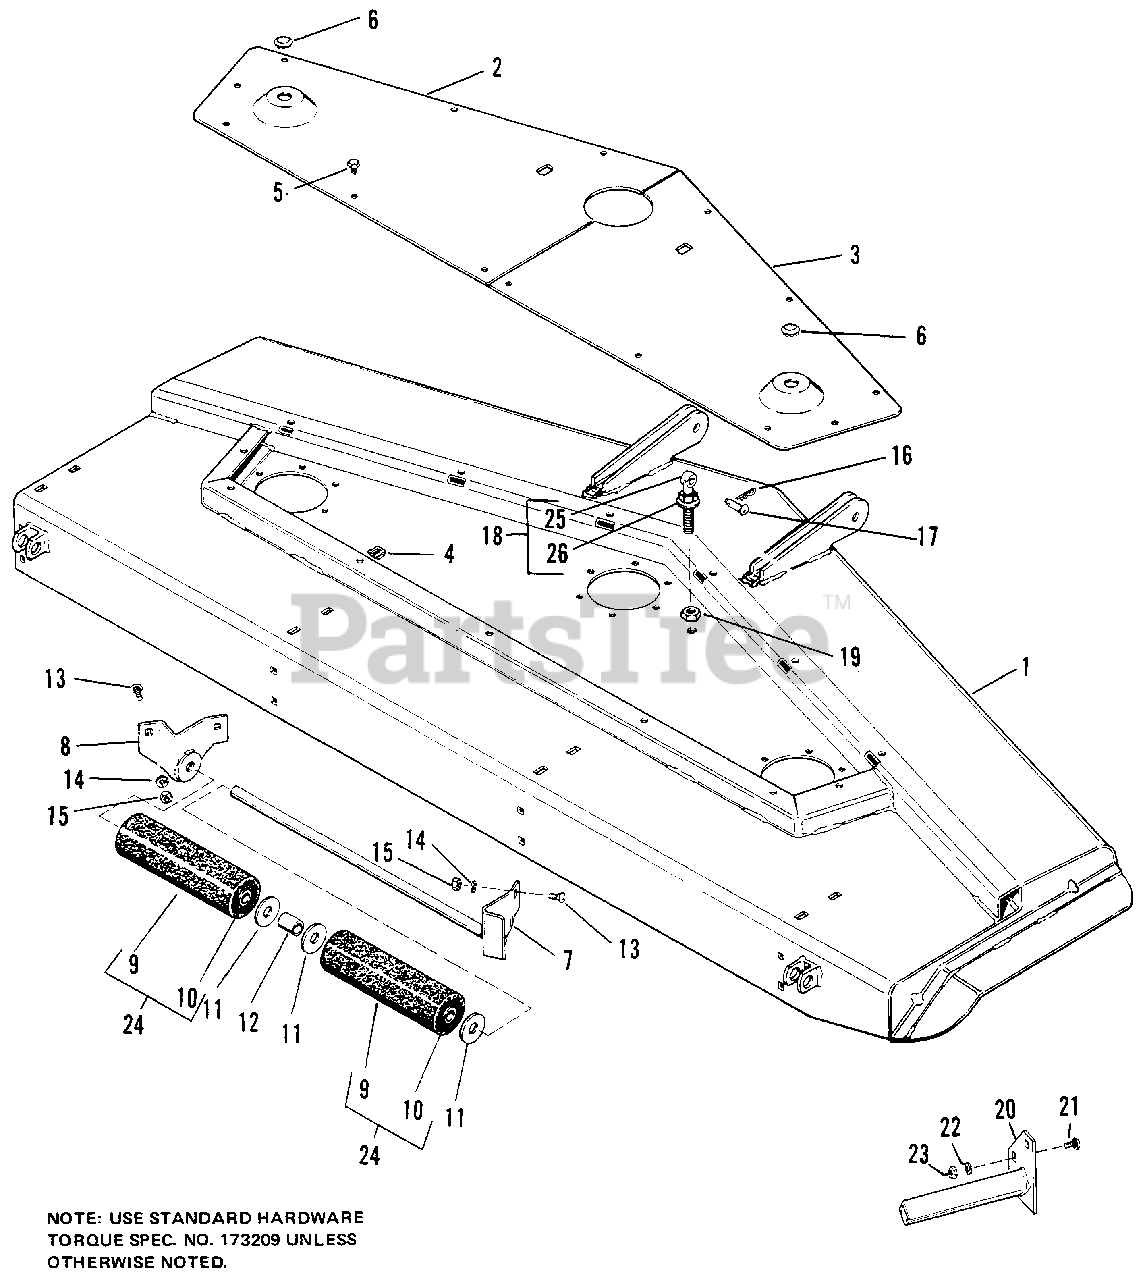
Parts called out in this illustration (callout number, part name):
1	DECK ASSY
2	PLATE, Cover, R.H.
3	PLATE, Cover, L.H.
4	NUT, Speed, Thin
5	SCREW, Self tapping, Hex, Wshr. Hd., 5/16 x 5/8
6	BUTTON, Plug
7	BRACKET & SHAFT ASSY
8	BRACKET ASSY
13	BOLT, Rd. Hd., Sq. Nk., 5/16-18 x 3/4
14	LOCKWASHER, Spring, 5/16
15	NUT Hex, 5/16-18
16	CLIP, Spring
17	PIN, Yoke, 3/8
18	BOLT ASSY, Eye
19	NUT, Hex, Lock, 7/16-14
20	GUARD ASSY, Stone
21	BOLT, Rd. Hd., Sq. Nk., 3/8-16 x 1
22	LOCKWASHER, Spring, 3/8
23	NUT, Hex, 3/8-16
24	ROLLER, w/Bushings
26	NUT, Flange, Whiz Lock, 7/16-14
